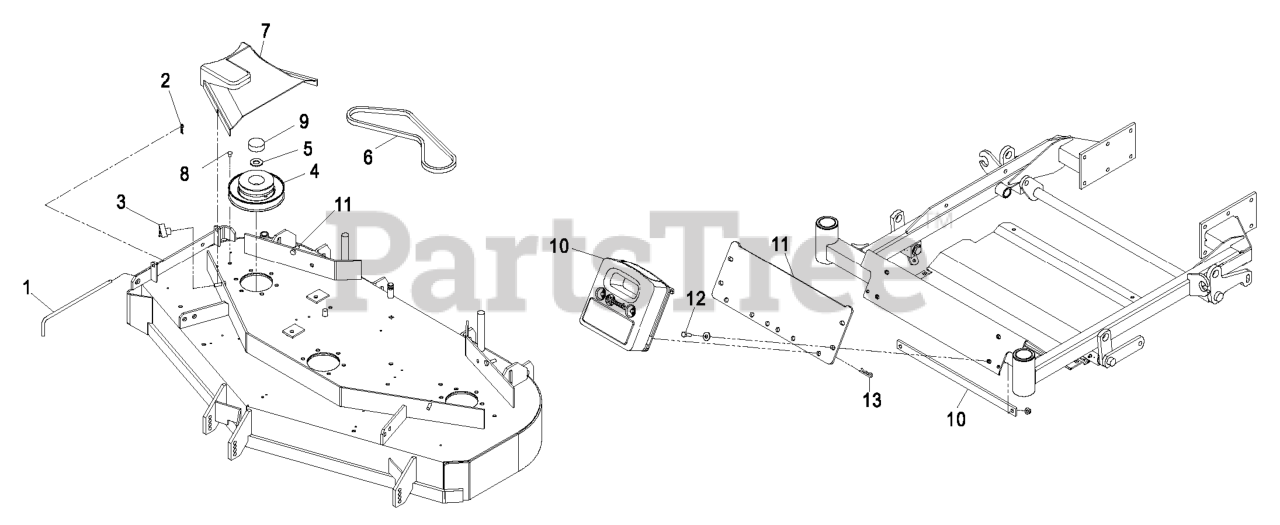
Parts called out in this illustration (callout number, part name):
1	PIN, CHUTE PIVOT PLTD
2	PIN-COTTER
3	KNOB-3 PRONG
4	SHEAVE, BLOWER DRIVE 52"
5	Washer, 5/8 SAE
6	BELT, BLOWER 52"DECK
7	COVER, BELT 52
8	SCREW-HH
9	PLUG, BLACK NYLON 1.75
10	Strap, Weight Mount
12	ASM,CAST WEIGHT
13	PLATE,WEIGHT ASM MOUNT
14	SCREW-HH
15	Hairpin, Cotter
